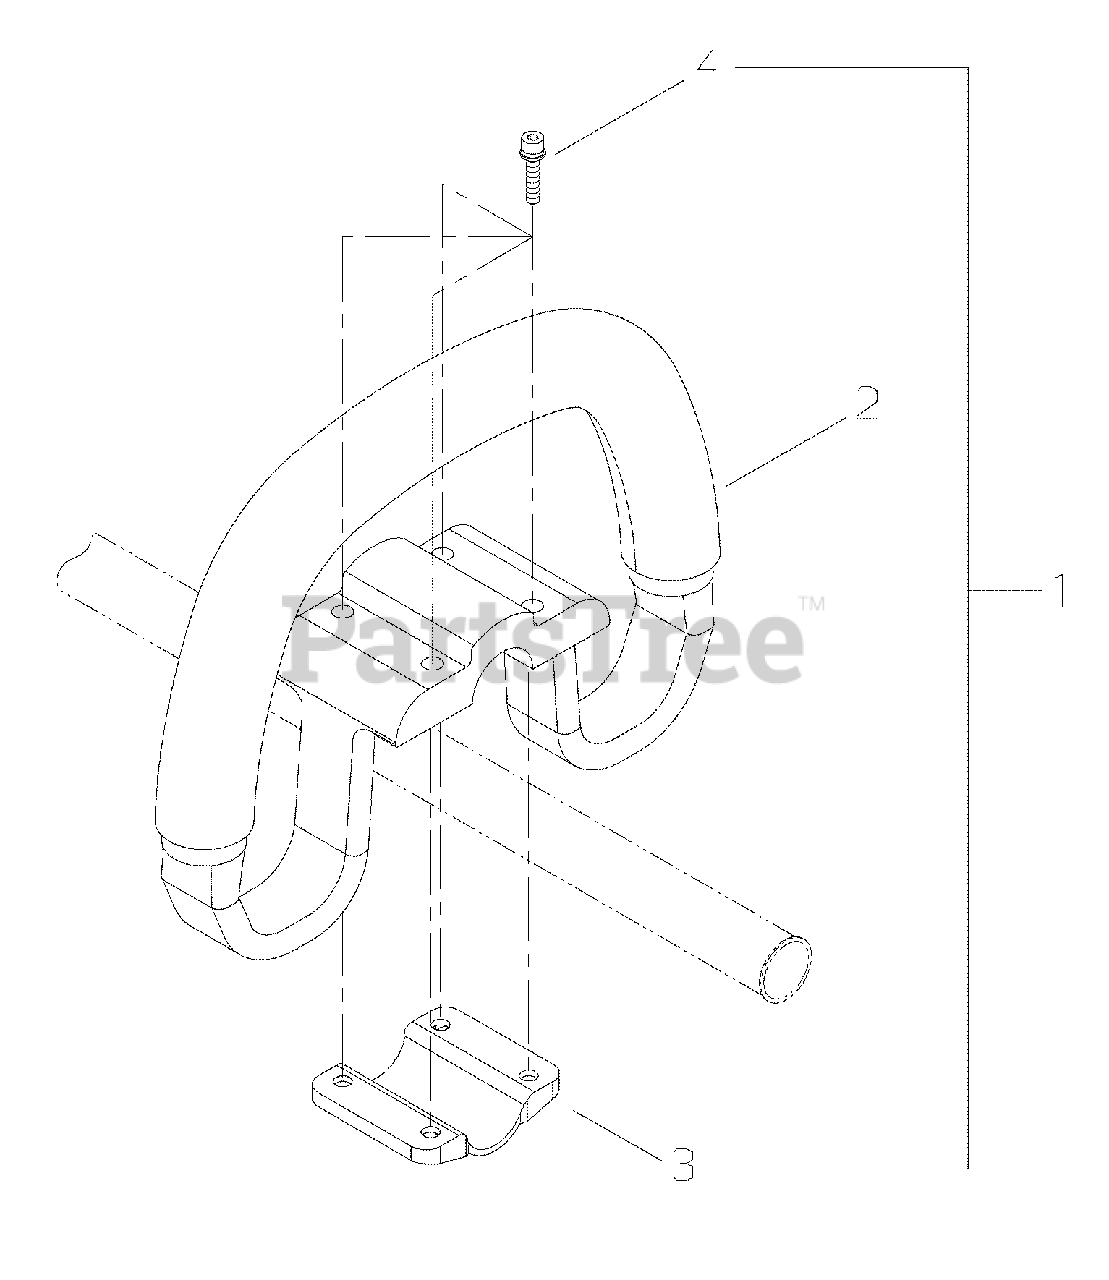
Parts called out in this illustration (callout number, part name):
1	HANDLE ASSY - SUPPORT
2	HANDLE
3	BRACKET, MOUNTING
4	BOLT M5×25
